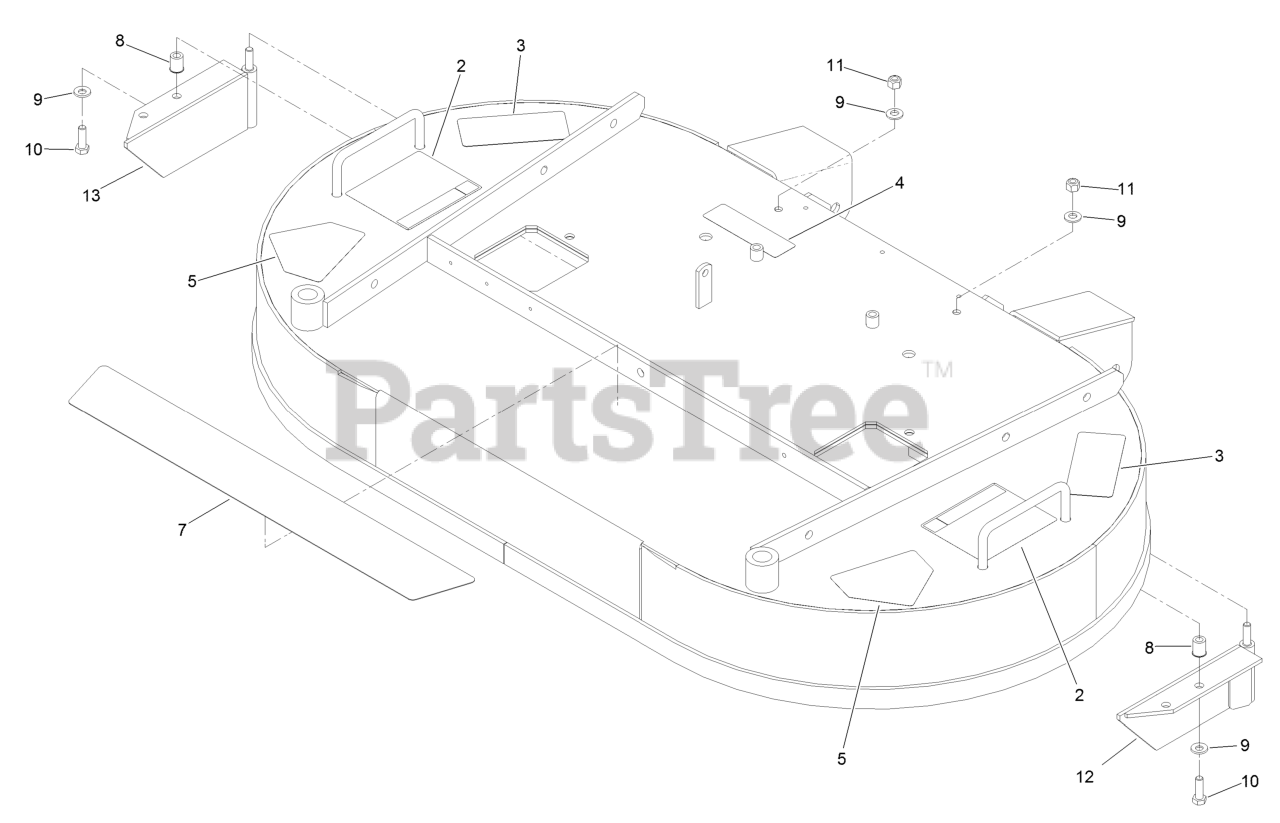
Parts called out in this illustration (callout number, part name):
2	DECAL-HEIGHT ADJUST, CUTT
3	DECAL-TORQUE, BLADE BOLT
4	DECAL-COVER, MISSING
5	DECAL-DANGER
7	PAD-SKID, ANTI
8	NUT-CLINCH
9	WASHER-SPRING
10	SCREW-HH
11	NUT-LOCK, NI
12	BAFFLE-LH
13	BAFFLE-RH
